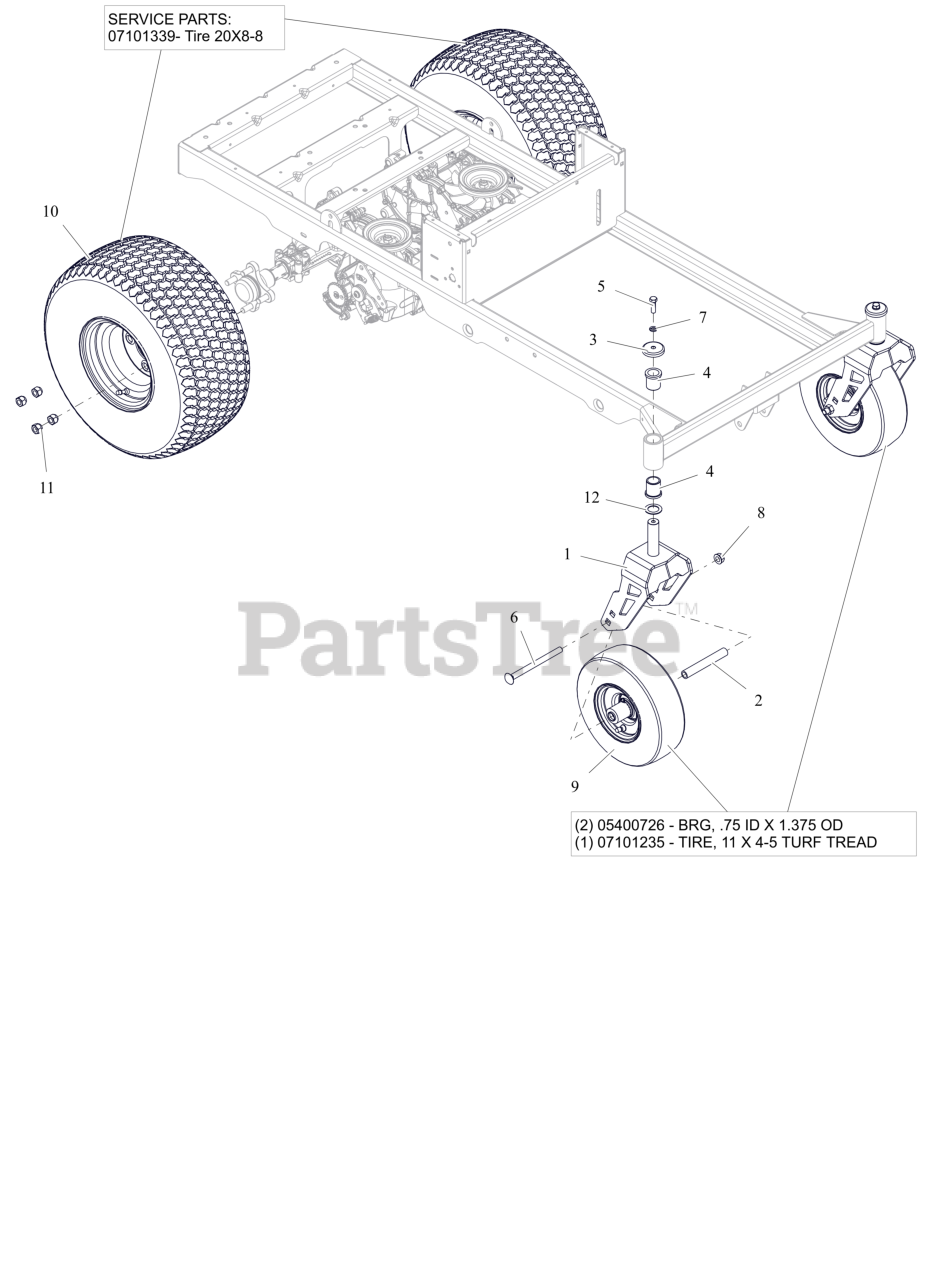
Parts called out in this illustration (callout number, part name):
1	WLDMT, CASTER FORK-XD (ORANGE)
2	SPACER, ROLLED WHEEL
3	SHIELD, AXLE BEARING
4	BSHG-FLG 1.00X1.25X1.50X1.50
5	BLT, HEX .38-16X1.25 G5 ZCC
6	BLT, RHSN .50-13X6.50 G5 ZCC
7	WSHR,LK-REG .375X.094 ZCC
8	NUT-LK-CTR-FLG .500-13 GG ZCC
9	ASM, WHL/TIRE 11X4.00-5
9	BRG, .75 ID X 1.375 OD
9	TIRE, 11X4-5 TURF TREAD
10	ASSM TIRE\WHEEL, 20 X 8 -8
10	TIRE, 20 X 8-8
11	NUT, WHEEL .50-20 ZCC
12	WSHR-HRD-THRS 1.007X1.542X.062
